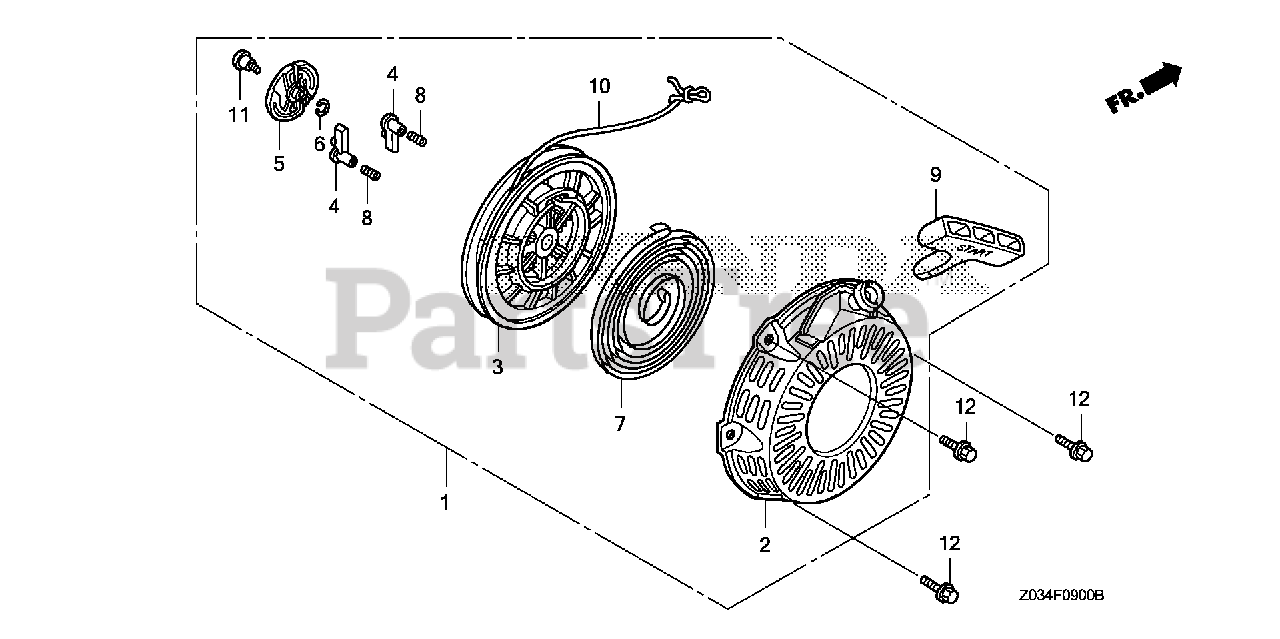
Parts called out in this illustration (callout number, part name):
1	STARTER ASSY., RECOIL *R280* (POWER RED)
2	CASE, RECOIL STARTER *R280* (POWER RED)
3	REEL, RECOIL STARTER (NATURAL)
4	RATCHET, STARTER
5	GUIDE, RATCHET
6	SPRING, FRICTION
7	SPRING, RECOIL STARTER
8	SPRING, RETURN
9	KNOB, RECOIL STARTER
10	ROPE, RECOIL STARTER
11	SCREW, SETTING
12	BOLT, FLANGE (6X12) (CT200)
